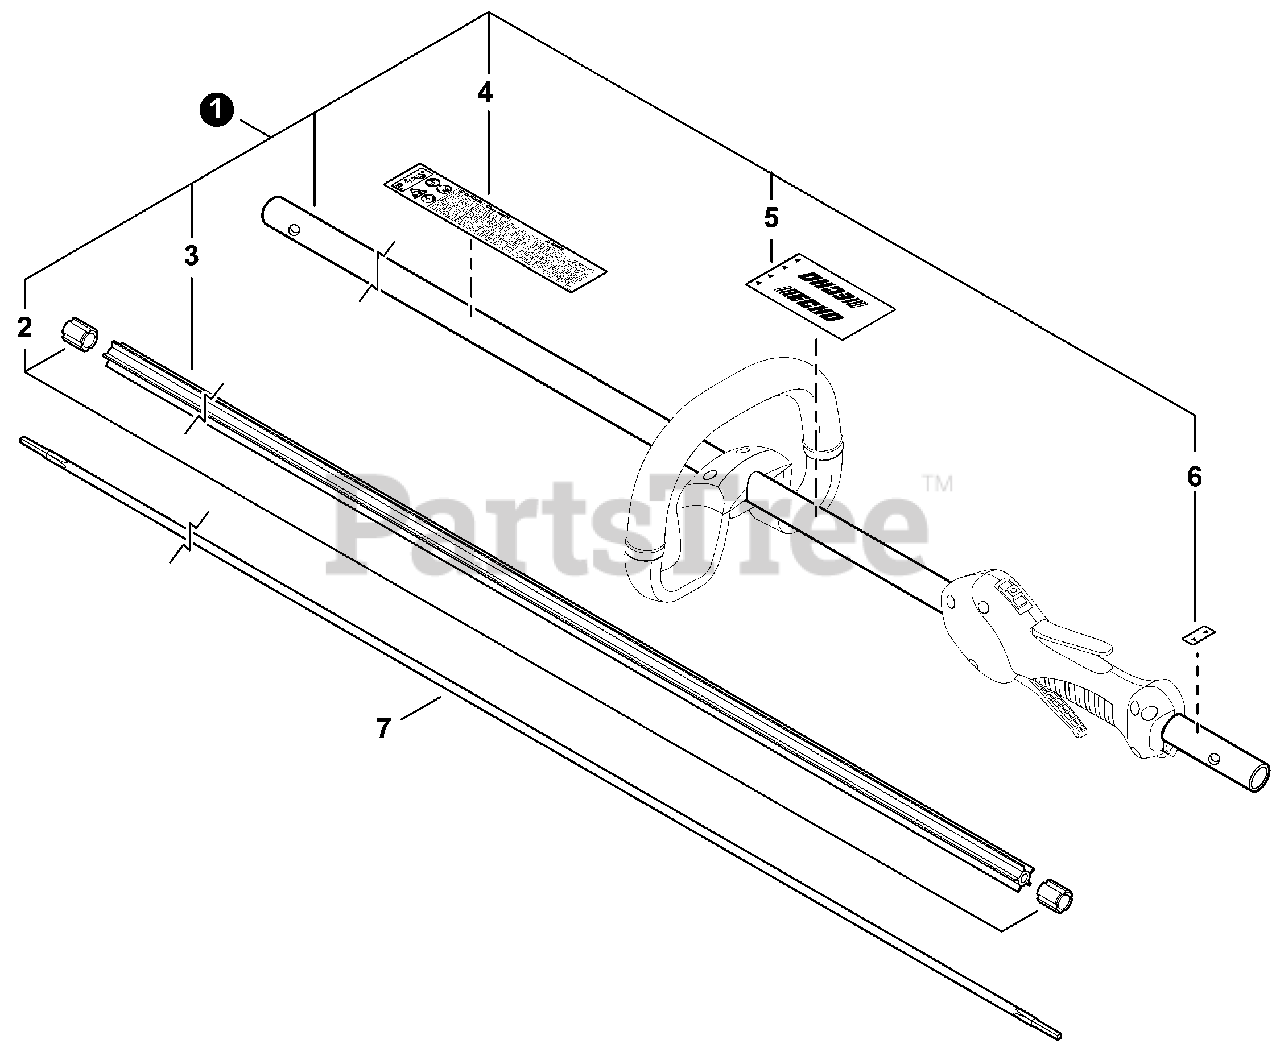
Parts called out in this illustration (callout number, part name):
1	MAIN PIPE ASSY
3	LINER, FLEXIBLE 21.6×1420
4	LABEL, CAUTION
5	LABEL, HANDLE LOCATION
6	LABEL - ALIGNMENT
7	DRIVESHAFT - FLEXIBLE L= 1522
